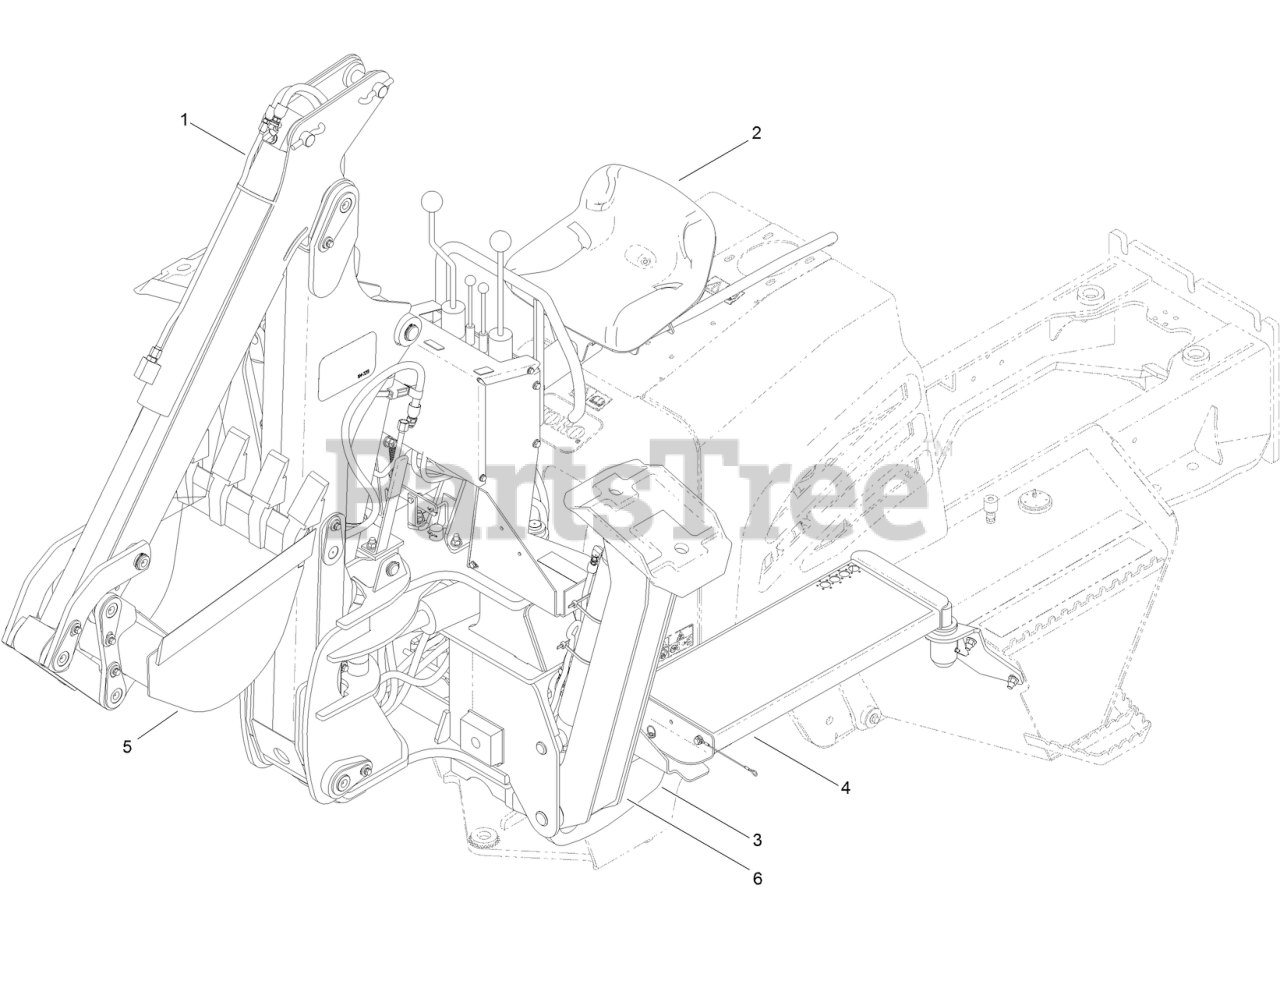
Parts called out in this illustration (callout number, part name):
1	BACKHOE ASM
2	ATTACH-SEAT/BUCKET KIT
3	ATTACH KIT
4	WALKWAY KIT
5	BUCKET-TRENCHING, 18IN
6	STABILIZER-WING TYPE KIT
